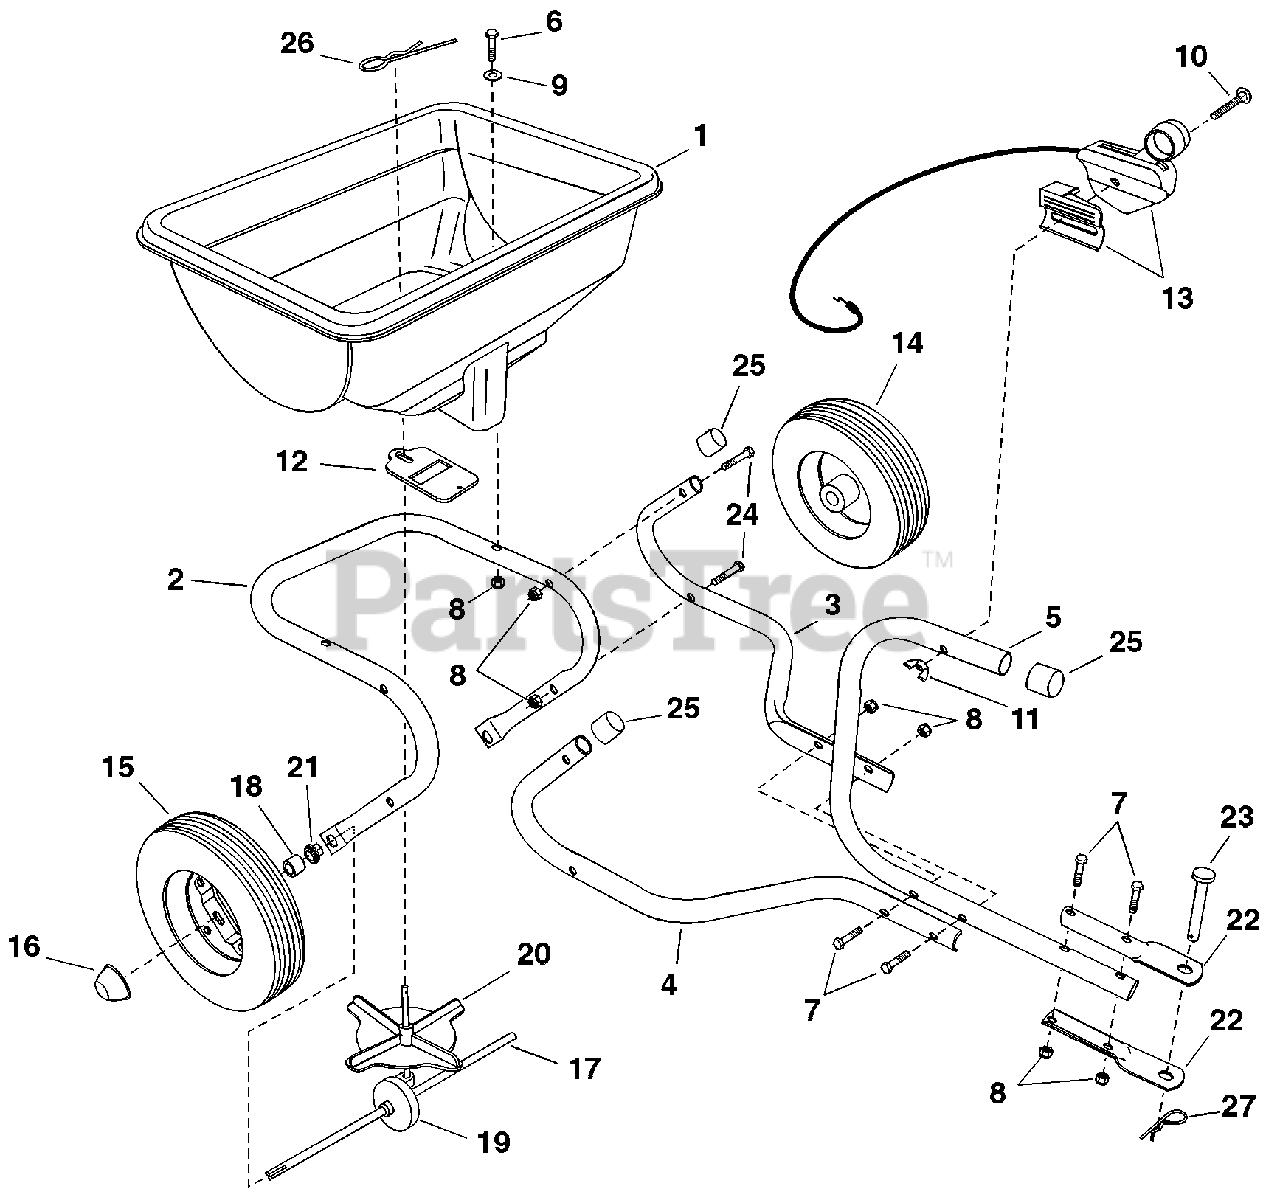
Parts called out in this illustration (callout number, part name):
2	Frame Tube
3	Hitch Tube
4	Hitch Tube
5	Hitch Control Tube
6	Hex Bolt, 1/420 x 1-1/2"
7	Hex Bolt, 1/420 x 1-3/4"
8	Nylock Nut, 1/420
9	Washer, 1/4 Std
10	Carriage Bolt 1/420 x 2"
11	Nylon Wing Nut 1/4-20
12	Flow Slide
13	Control Cable Asembly
15	Drive Wheel
16	Hub Cap
19	Gearbox
20	Impeller
21	Hex Flange Bearing
22	Hitch Bracket
23	Hitch Pin
24	Hex Bolt, 1/4-20 x 2"
25	Vinyl Cap
26	Hairpin, Agitator
27	Hairpin, Cotter
